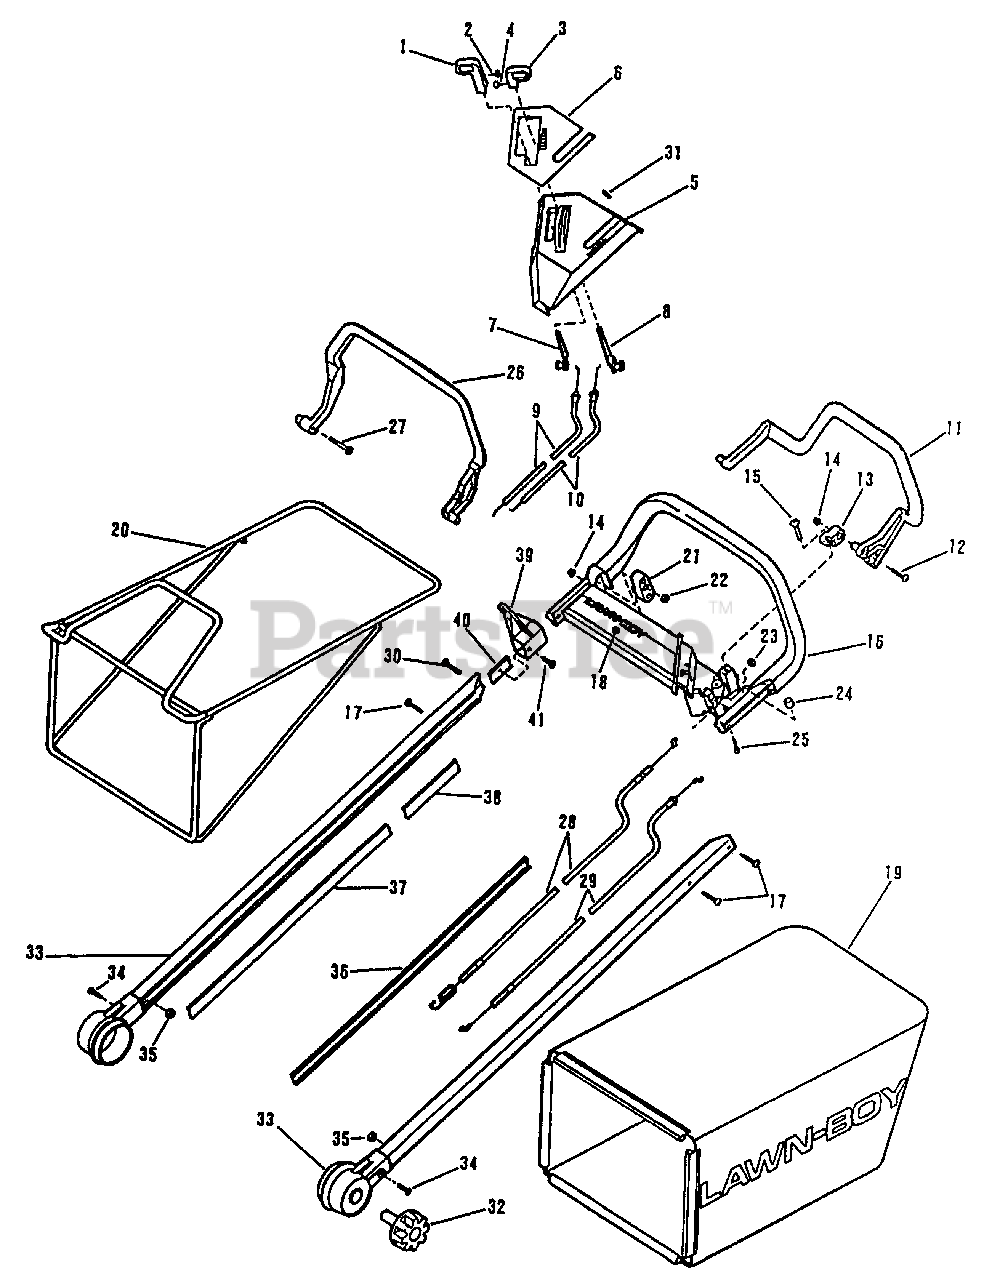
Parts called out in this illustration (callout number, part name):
1	Knob Assembly-Gear Select
2	Set Screw
3	Knob Assembly-Throttle
4	Set Screw
5	Upper Cover Assy (ZMRA)
6	Plate
7	Gear Select Lever
8	Throttle Lever
9	Cable Assembly-Gear Select
10	Cable Assembly-Throttle
11	Self-propelled Bail
12	Screw
13	Bail Pivot
14	Locknut
15	Screw
16	Handle and Decal Assy (ZMRA)
17	Thread Forming Screw
18	Decal-Lawn-Boy
19	Rear Grass Bag
20	Frame
21	Bail Block
22	Nut
23	Nut-Self-propelled Cable
24	Bumper
25	Screw
26	Engine Brake Bail
27	Screw
28	Cable Assembly-Self-propelled
29	Cable Assembly-Engine Brake
30	Screw
31	Plug
32	Knob-Handle Mounting
33	Handle Knuckle and Extrusion
34	Screw
35	Nut
36	Handle Insert-Cable Side
37	Handle Insert
38	Handle Insert
39	Rope Guide
40	Nut Plate
41	Screw
